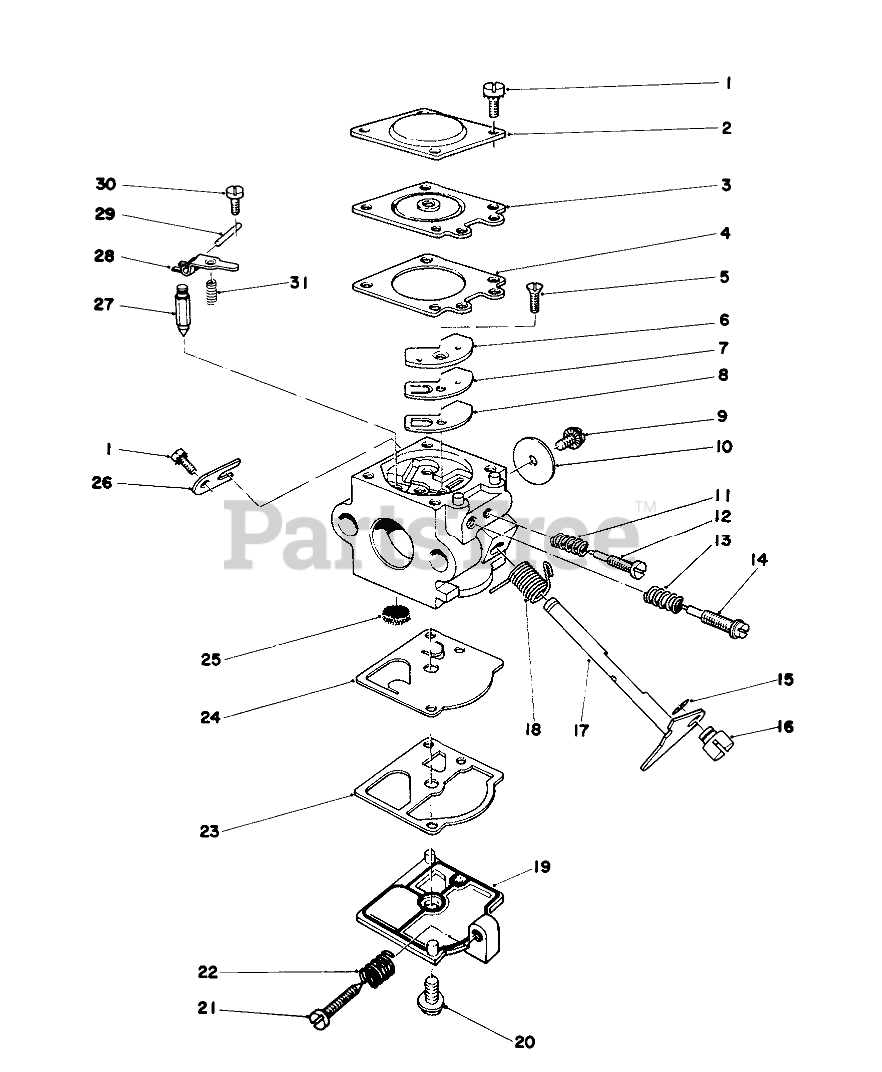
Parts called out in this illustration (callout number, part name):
1	Screw
2	Cover, Diaphragm
3	METERING DIAPHRAGM
4	Gasket, Diaphragm
5	Screw-Circuit Plate
6	Plate, Circuit
7	Diaphragm Circuit Plate
8	Gasket-Circuit Plate
9	Screw
10	Valve Throttle
11	Spring, Needle
12	Idle Needle
13	Spring, HS Needle
14	Needle, High Speed
16	Swivel
17	THROTTLE SHAFT ASM
18	Spring-Throttle Lever
19	Cover, Fuel Pump
20	Screw
21	Screw, Idle Adjust
22	Spring, Idle Screw
23	PUMP GASKET
24	Diaphragm Fuel Pump
25	Screen Inlet
26	Clip Throttle Shaft
27	INLET NEEDLE VALVE
28	Lever Metering
29	Metering Lever Pin
30	Screw-Metering Pin
31	Spring, Lever
